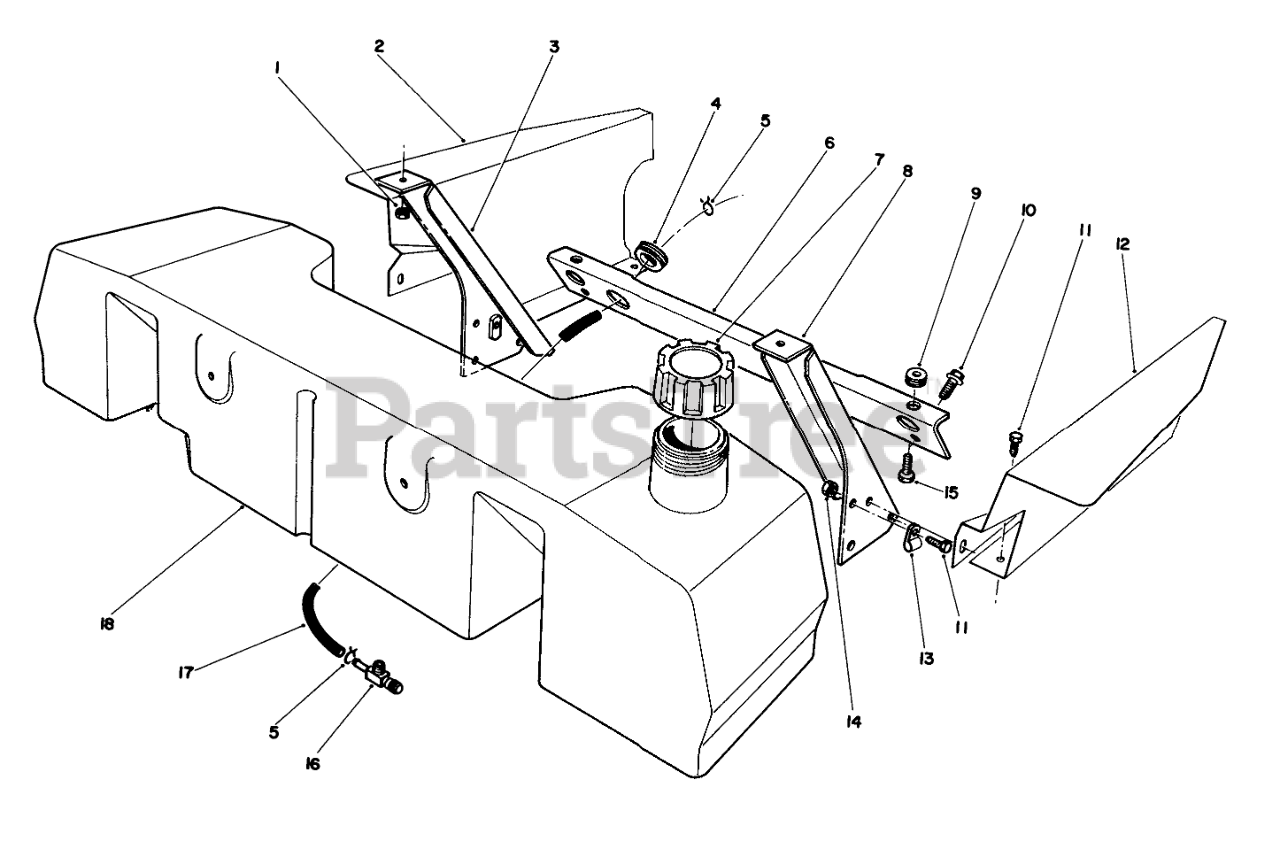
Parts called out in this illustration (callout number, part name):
1	NUT-LOCK, NI
2	.INER - FENDER RH B
3	RIGHT REAR SUPPORT WAB
4	GROMMET
5	FUEL HOSE CLAMP
6	GAS TANK SUPPORT B
7	GAS CAP ASM
8	LEFT REAR SUPPORT WA B
9	GROMMET
10	SCREW-HHF
11	SCREW-HH
12	LINER-FENDER LH B
13	R-CLAMP
14	NUT-LOCK, NI
15	SCREW-PPH
16	FUEL SHUTOFF
17	HOSE-FUEL
18	GAS TANK ASSEMBLY
